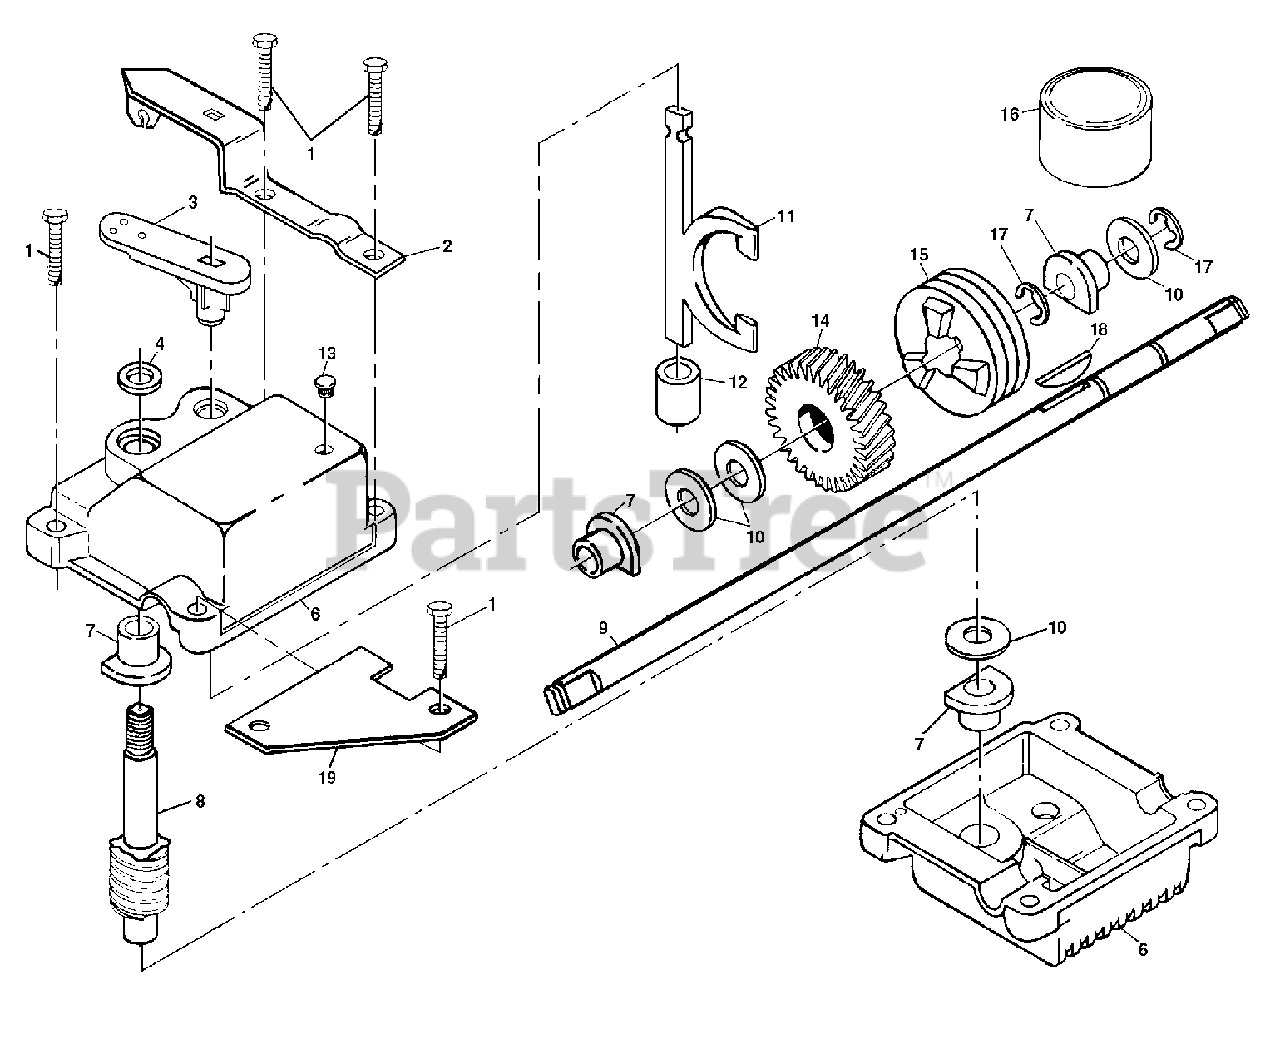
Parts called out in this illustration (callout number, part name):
1	Control Cable Assembly
3	Flanged Locknut 3/8-16
4	Hex Washer Head Screw 1/4-20 x 2.12
6	Spring Retainer
8	Hubcap
11	Wheel & Tire Assembly
12	E-Ring
13	Pinion
14	Dust Cover
16	Washer 1/2 x 1-1/2 x .134
18	Selector Knob
26	Pan Head Tapping Screw#10-24 x 2-3/4
27	Pan Head Screw #10-24 x 1- 3/4
28	Drive Cover
31	Hex Flange Nut
32	Drive Pulley
35	Wheel Adjuster Assembly (Left)
36	Gear Case Assembly
37	Spring
38	Locknut 1/4-20
40	Spring
41	Wheel Adjuster Assembly (Right)
53	Frame Assembly
54	Grass Catcher
55	Driveshaft Cover
60	Nut
